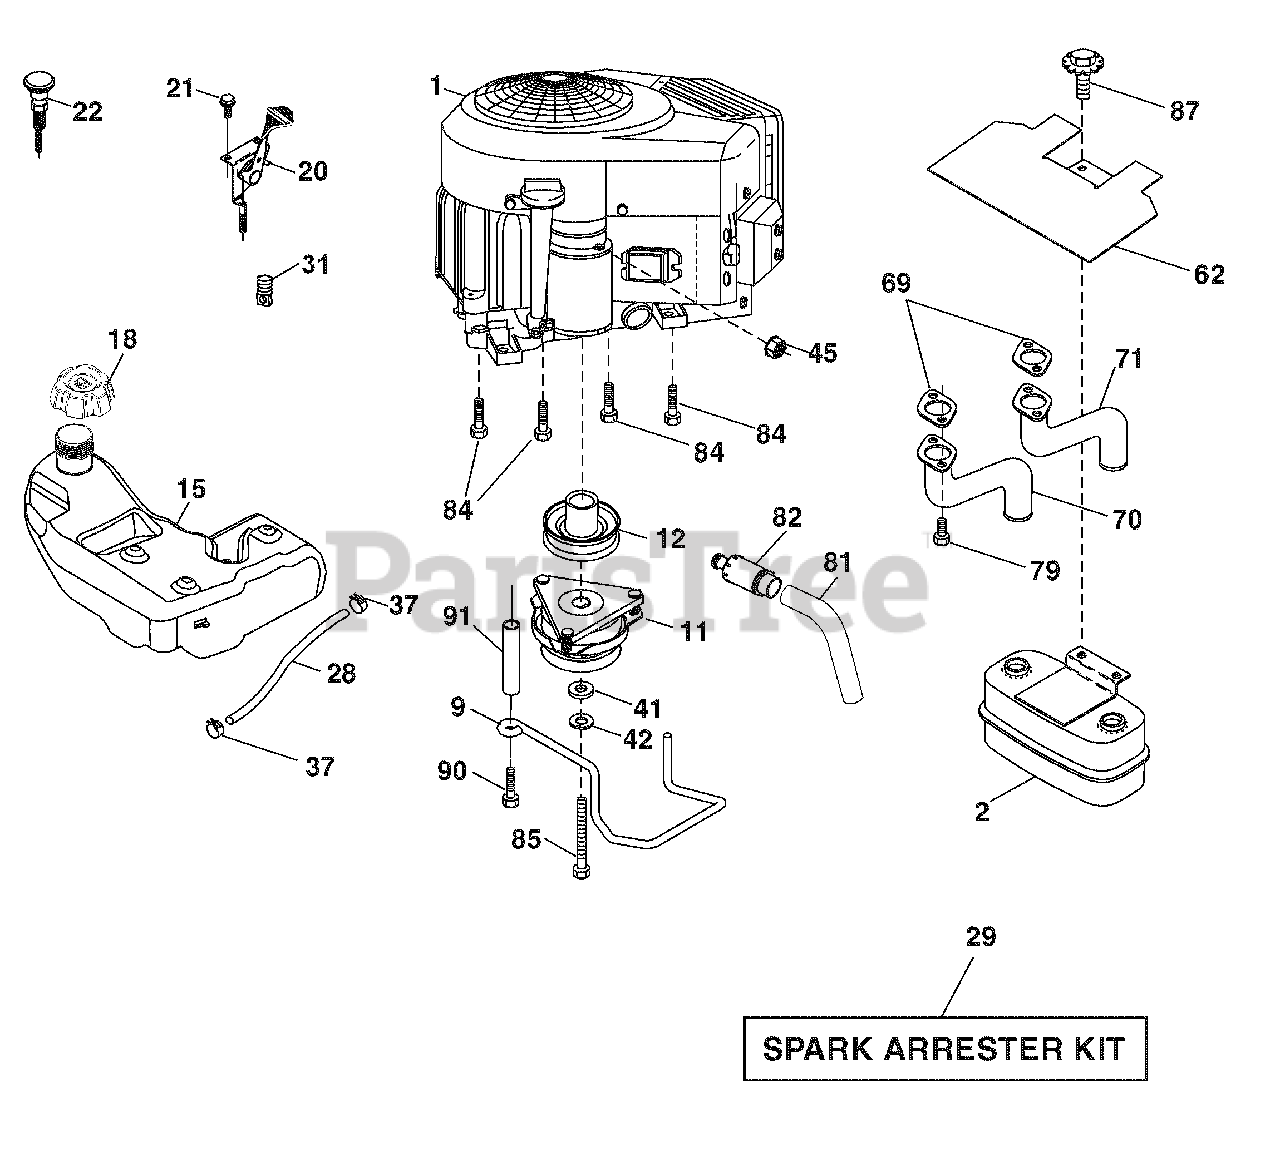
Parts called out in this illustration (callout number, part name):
9	Keeper Belt Engine
11	Clutch Electric
12	Pulley Engine
15	Tank Fuel 4.0
18	Cap Asm
20	Control Throttle
21	Screw #10 x 0.750 BOS Thread
22	Control Choke
28	Fuel Line
29	Spark Arrester Kit
31	Clip Push-In Hinged
37	Clamp Hose
41	Washer 1-1/2 OD x 15/32 ID x .250
42	Washer Lock 7/16
45	Nut Keps Hex 1/4-20 unc
62	Shield Heat Muffler
70	Tube Exhaust LH
71	Tube Exhaust RH
79	Screw Socket Head
81	Tube Drain Oil Easy
82	Plug Drain Oil
84	Screw 3/8-16 x 1-1/4
85	Bolt Hex 7/16-20 x 3.75 Gr. 5
86	Nut Hex M8-1.25
87	Bolt 5/16-18 unc x 1 w/Sems
90	Screw 3/8-16 x 1
91	Bushing 1.375 OD
